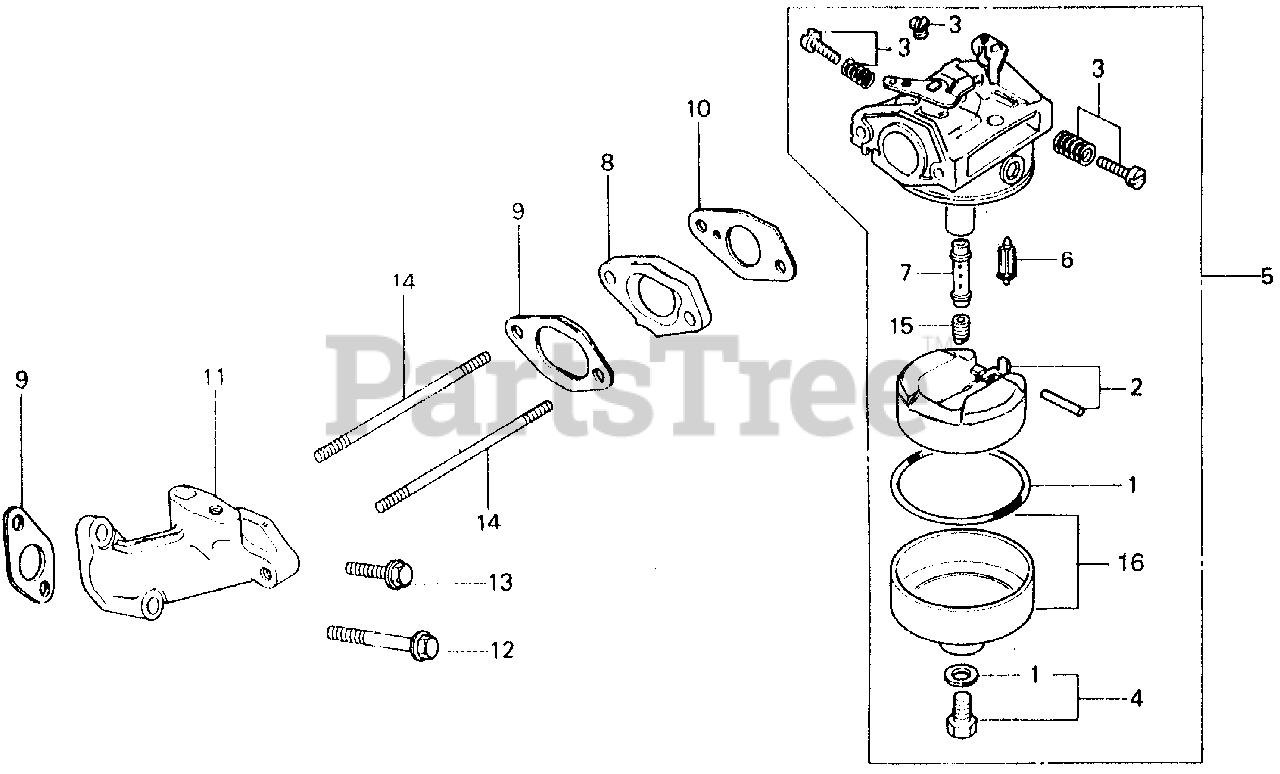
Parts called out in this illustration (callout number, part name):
1	GASKET SET
3	SCREW SET A
3	SCREW SET A (NOT AVAILABLE)
4	SCREW SET B
4	SCREW SET
5	CARBURETOR ASSY. (BB31A B) (NOT AVAILABLE)
5	CARBURETOR ASSY. (BB31A C)
6	VALVE, FLOAT
7	NOZZLE, MAIN (NOT AVAILABLE)
8	INSULATOR, CARBURETOR
9	GASKET, INSULATOR
10	GASKET, CARBURETOR
11	MANIFOLD, IN. (NOT AVAILABLE)
12	BOLT, FLANGE (6X50)
13	BOLT, FLANGE (6X20) (CT200)
14	BOLT, STUD (6X141) (NOT AVAILABLE)
15	JET, MAIN (#70)
15	JET, MAIN (#72)
15	JET, MAIN (#75)
16	CHAMBER SET, FLOAT
16	CHAMBER SET, FLOAT (NOT AVAILABLE)
